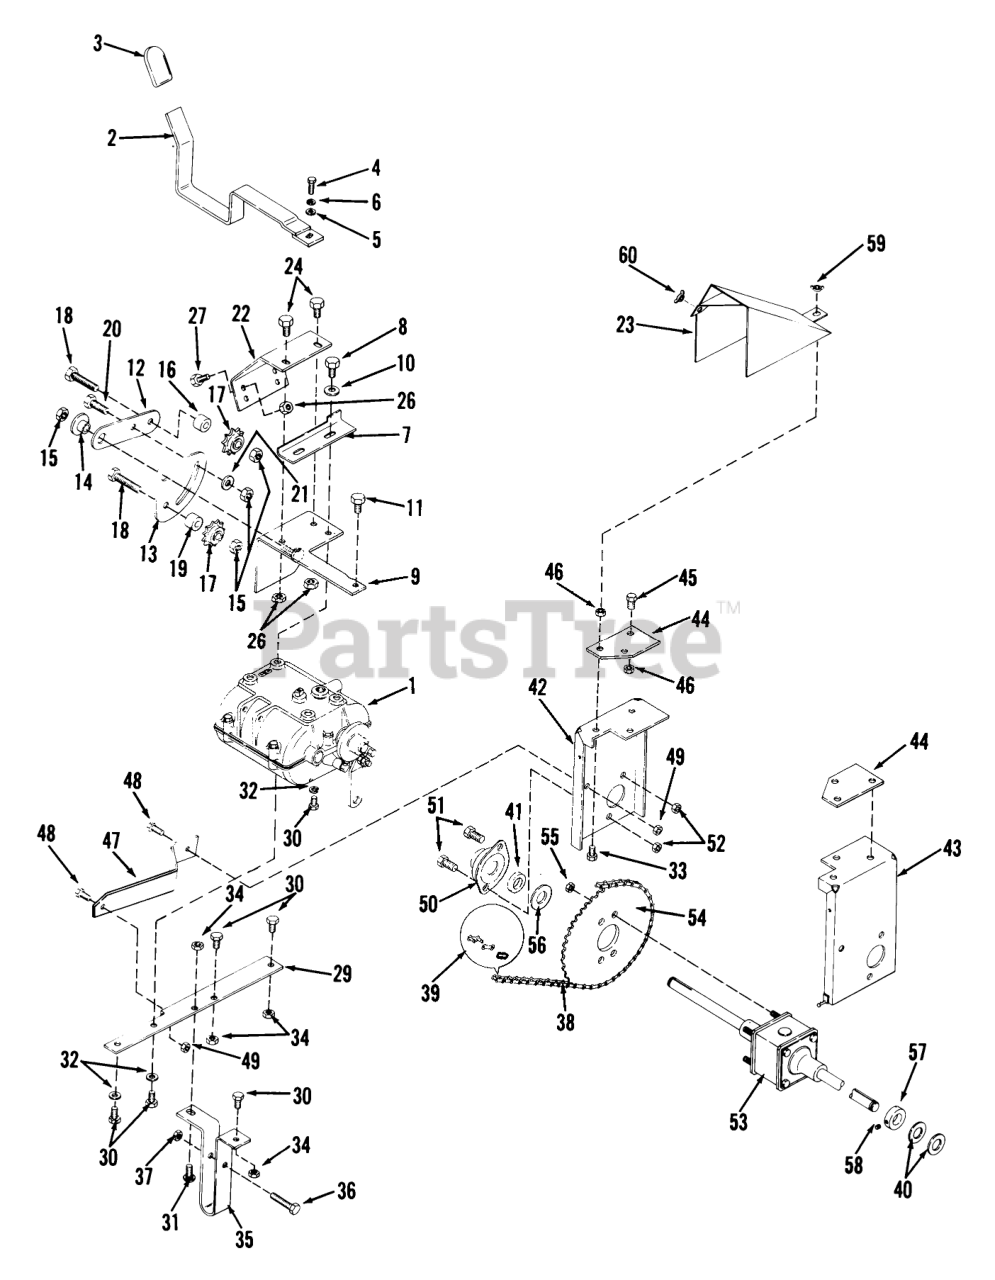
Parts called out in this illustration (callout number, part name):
1	SEE SEVICE BULT #228
5	WASHER
10	WASHER 5/16 SAE
11	Screw
14	SPACER-BUSHING
19	SPACER
40	WASHER
54	SPROCKET
56	WASHER
